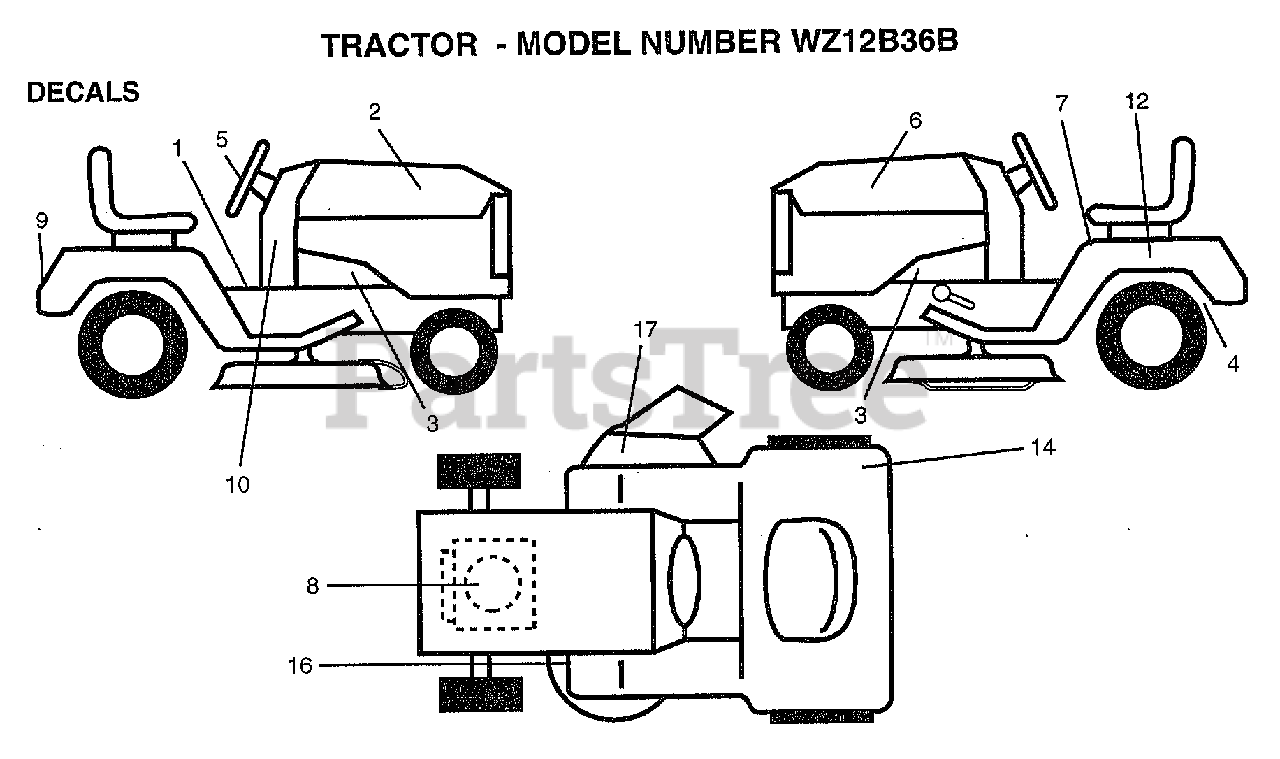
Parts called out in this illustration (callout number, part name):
1	DECAL CLUTCH/BRAK
2	DECAL.HOOD.RH
3	"DECAL CHASSIS,HOT"
4	DECAL.DRAWBAR.LDL
5	DECAL.INS.STRG/WH
6	DECAL.HOOD.LH
7	DECAL.READ.O.MANU
9	DECAL.FENDER
10	DECAL.EURO.ST.CE.
12	DECAL.BATRY.3-3908
16	DECAL.DANGER.CUTF
17	DECAL.V.BELT
